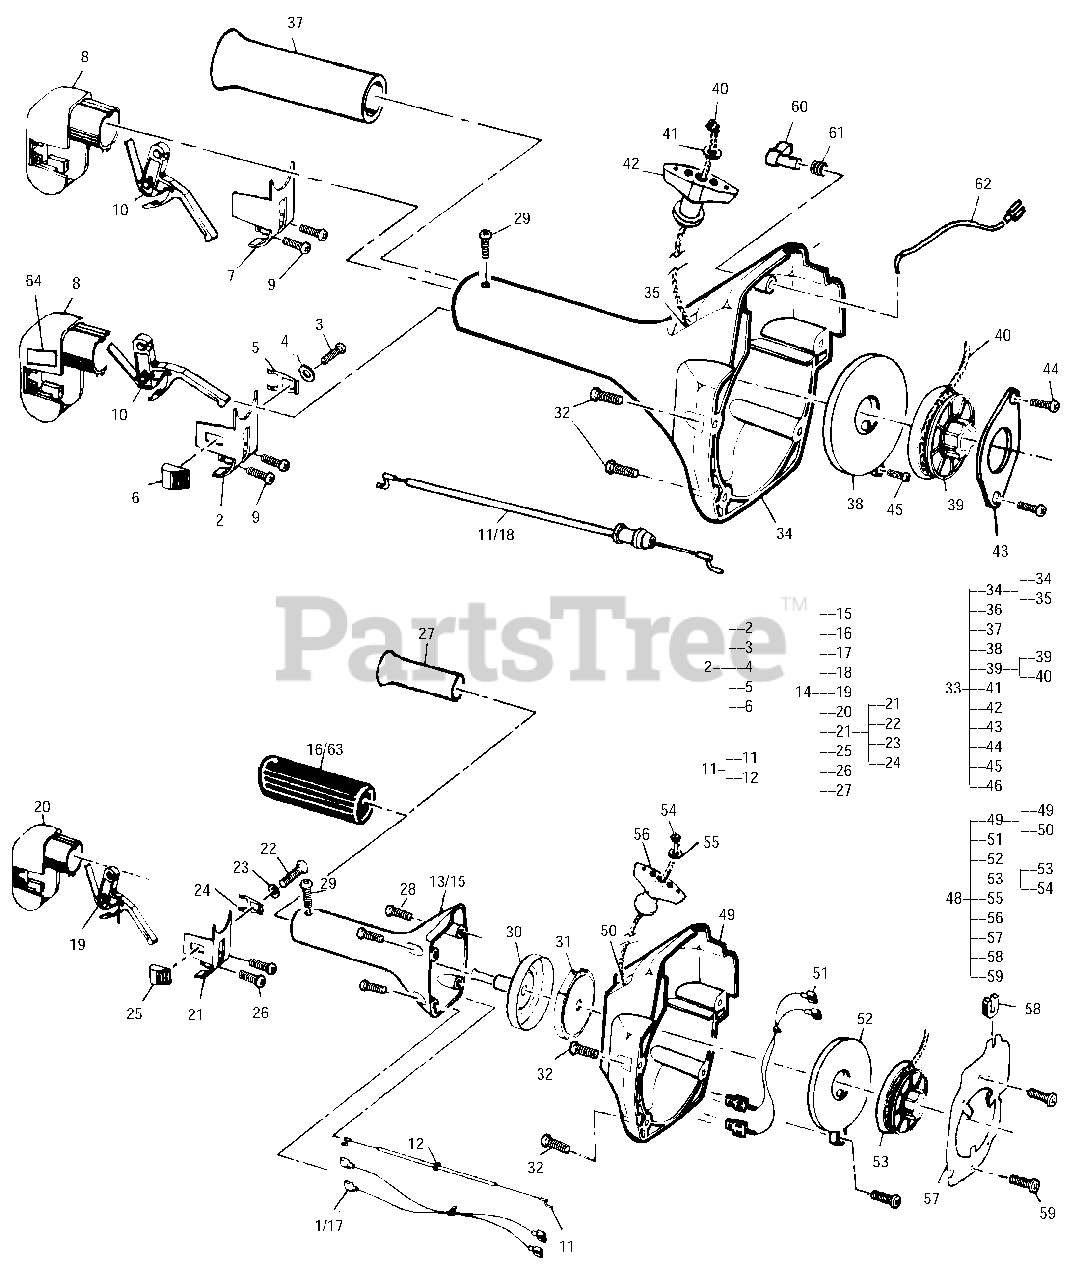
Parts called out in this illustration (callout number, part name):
1	Wire Asy, Switch
2	Cover, Asy, Switch
3	Screw, 8-16 x .375 Plastite
4	Washer, Flat, .180 ID max
5	Contact, Switch
6	Button, Stop Switch
7	Cover, Switch Housing
8	Trigger Hsg Asy, 22mm, 28/32
9	Screw, 6-19 x .62 Fl Hd Plastite
10	Trigger, Throttle
11	Throttle Cable, Direct Drive
11	Throttle Cable, Clutch Drive
12	Nut, Speed, .188 ID
14	Housing Asy, Clutch, 7/8 in.(Black)
15	Housing, Clutch 7/8 (Black)
17	Wire Asy, Switch
18	Cable Asy, Throttle
19	Trigger, Throttle
20	Trigger Hsg Asy, 22mm (28/32)
21	Cover Asy, Switch
22	Screw, 8-16 x .375 Plastite
23	Washer, Flat, .180 ID max
24	Contact, Switch
25	Button, Stop Switch
26	Screw, 6-19x.62 Fl Hd Plast
27	Sleeve, Protecting
28	Screw, 10-14 x 1.0 Pn Hd
29	Screw, 12-11 x .5 Pn Hd Torx
30	Drum, Clutch, Heat Treated
31	Kit, Clutch
32	Screw, 10-24 x .625
33	Starter Asy (Black) Direct Drive
34	Housing/Eyelet, Starter DD (Black) 1
35	Rope Guide
36	Wire Asy, Switch
37	Sleeve, Protecting
38	Spring, Starter Rewind
39	New Direct Drive Drum/Rope Asy
40	Rope, Starter, 46 in.
41	Washer, Nylon
42	Handle Starter
43	Pulley, Retained, Direct Drive
44	Screw, 8-16 Plastite
45	Screw, Spring Retainer
48	Starter Asy Clutch Drive (Black)
49	Housing, Starter Cl Dr (Black)
50	Rope Guide
51	Wire Asy, Starter Hsg, Clutch Dr
52	Spring Asy, Package
53	Drum/Rope Asy
54	Rope, Starter, 46 in.
55	Washer, Nylon
56	Handle, Starter
57	Plate, Baffle, Clutch Drive
58	Grommet, H/T Lead
59	Screw, 8-16 Plastite
60	Button, Stop
61	Spring, Stop Button
62	Wire Asy, Switch
63	Grip
